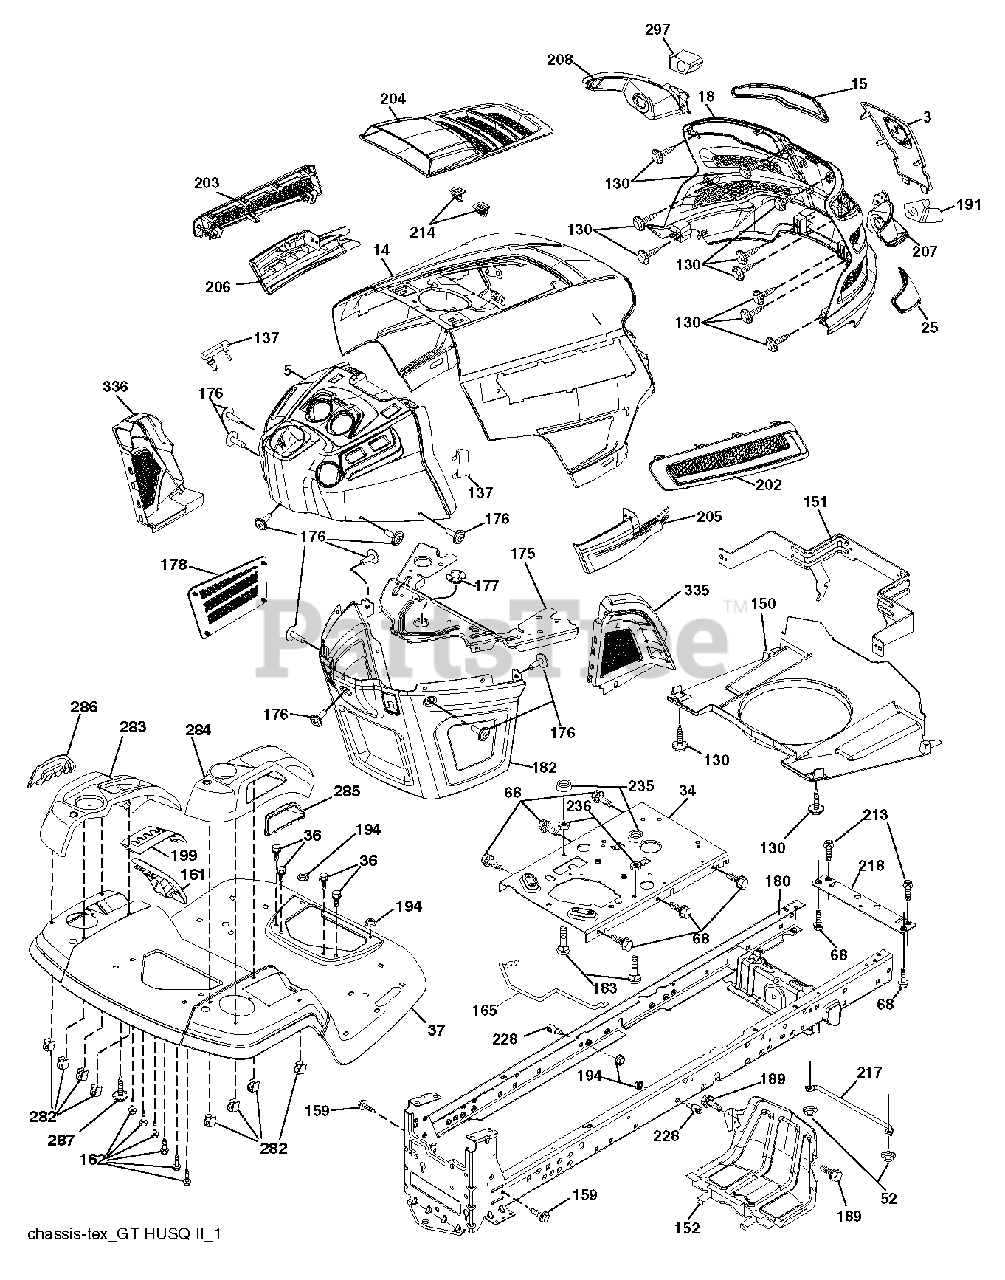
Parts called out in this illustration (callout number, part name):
3	APPLIQUE.SUBASM.GT.HUSQ.II
5	DASH.UPPER.ASSY.GT2.DUAL
14	HOOD.ASM.HUSQVARNA.GT.TEX.422
15	LENS.HEADLIGHT.LH.GTII.2011
18	GRILLE.SUBASM.GT.HUSQ.II
25	LENS.HEADLIGHT.RH.GTII.2011
34	PLATE.ENGINE.WELDED.CHASSIS
36	SCREW 5/16"
37	FENDER.TLT.FS.W/CPH/FW/RSF.ORN
52	LOCKNUT
68	SCREW LT
130	SCREW.#10 X 0.750.BOS
137	BUMPER DASH
150	AIR.DUCT.GTV.BLACK
151	BRACKET.PIVOT.HOOD.GT.HUSQ.II
152	SHIELD.BROWNING.PNT.GT.V2
159	SCREW, 3/8-16X3/4
161	WINDOW.FUEL.LT.HUSQ.TEX.498
162	SCREW.HI-LO.CONSOLE
165	SUPPORT.TANK.REAR.W/TEX
175	PLATE.CROSSMEMBER.HUSQ
176	SCREW.#10-24X5/8.RN.QU
177	BUSHING, STEERING
178	CARGO.ASM.NET.TXGT.W/C
180	CHASSIS
182	DASH.LOWER.COMMON.12V.ADAPTOR
183	BOLT.5/16-18X1-1/4 FULL THD
189	SCREW
191	INSERT.REFLECTIVE.RH.HUSQ.GTII
194	NUT LOCK HEX FLANGE 5/16-18
199	PLATE.DECK.LIFT.HUSQ.LT
202	VENT.SIDE.RH.GT.HUSQ.II.
203	VENT.SIDE.LH.GT.HUSQ.II.498
204	VENT.TOP.HUSQ.GT2
205	SIDE.TRIM.RH.GT.HUSQ.II
206	SIDE.TRIM.LH.GT.HUSQ.II.GRAY
207	BEZEL LIGHT.RH.GT.II.MYLAR
208	BEZEL LIGHT.LH.GT.II.MYLAR
213	BOLT
214	CLIP.RETAINER.TINNER.
217	ROD.PIVOT.HOOD
218	X-PIECE.HOOD.STOP.NON/
228	STUD.FASTNER.W/ANTI-ROTATE
235	SPACER FENDER
236	NUT.CENTERLOCK.5/16-
282	CLIP.RETAINER.CONSOLE.LT.HUSQ
283	CONSOLE.DECK.LIFT.R.SDFL.HUSQ
284	CONCOLE.CNTRL.PDL.HUSQ.LT.498
285	CONSOLE INSERT RH
286	CONSOLE.INSRT.LH.HUSQ.LT.BLACK
287	SCREW 1/4X20
297	INSERT.REFLECTIVE.LH.HUSQ.GTII
335	COVER.RH.CLOSE.OUT.BLACK
336	COVER.LH.CLOSE.OUT
